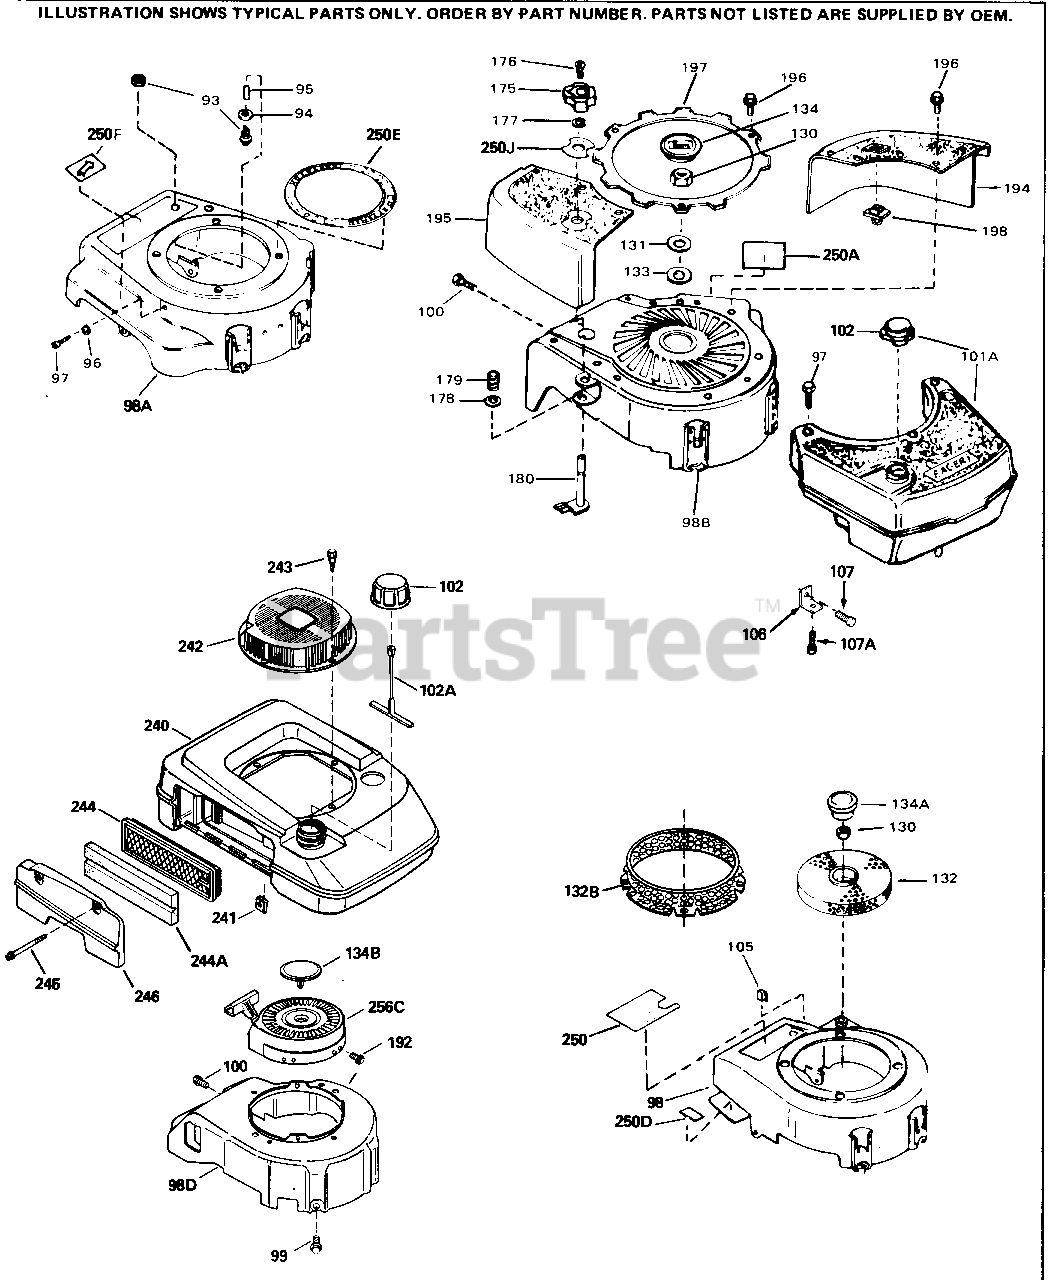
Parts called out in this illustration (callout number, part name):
98B	Housing, Blower
99	Screw, Hex washer hd. Powerlok thread ,
101A	Tank Assy., Fuel (Red Poly) (1-1/2 qt s.)
102	Cap, Fuel filler (Red Plastic) (Spurt
102	Cap, Fuel filler (White Plastic) (Sta ndard)
105	Clip, Ground wire
130	Nut, Flywheel
131	Washer, Belleville
133	Washer, Flat
134	Plug, Screen
175	Knob, Control
176	Screw, Oval hd. self-tap, 8-32 x 1/2
177	Ring, Retaining
178	Washer, Flat
179	Spring, Compression
180	Control, Lever
192	Screw, Hex washer hd. taptite, 1/4-20 x 5/8
194	Cover, Engine (Starter side)
195	Cover, Engine (Carb. side)
196	Screw, Hex washer hd. self-tap, 10-32 x 7/8
197	Ring, Grill
198	Pulley Assy., Starter rope
250	Decal, Instruction
250J	Decal, Control
